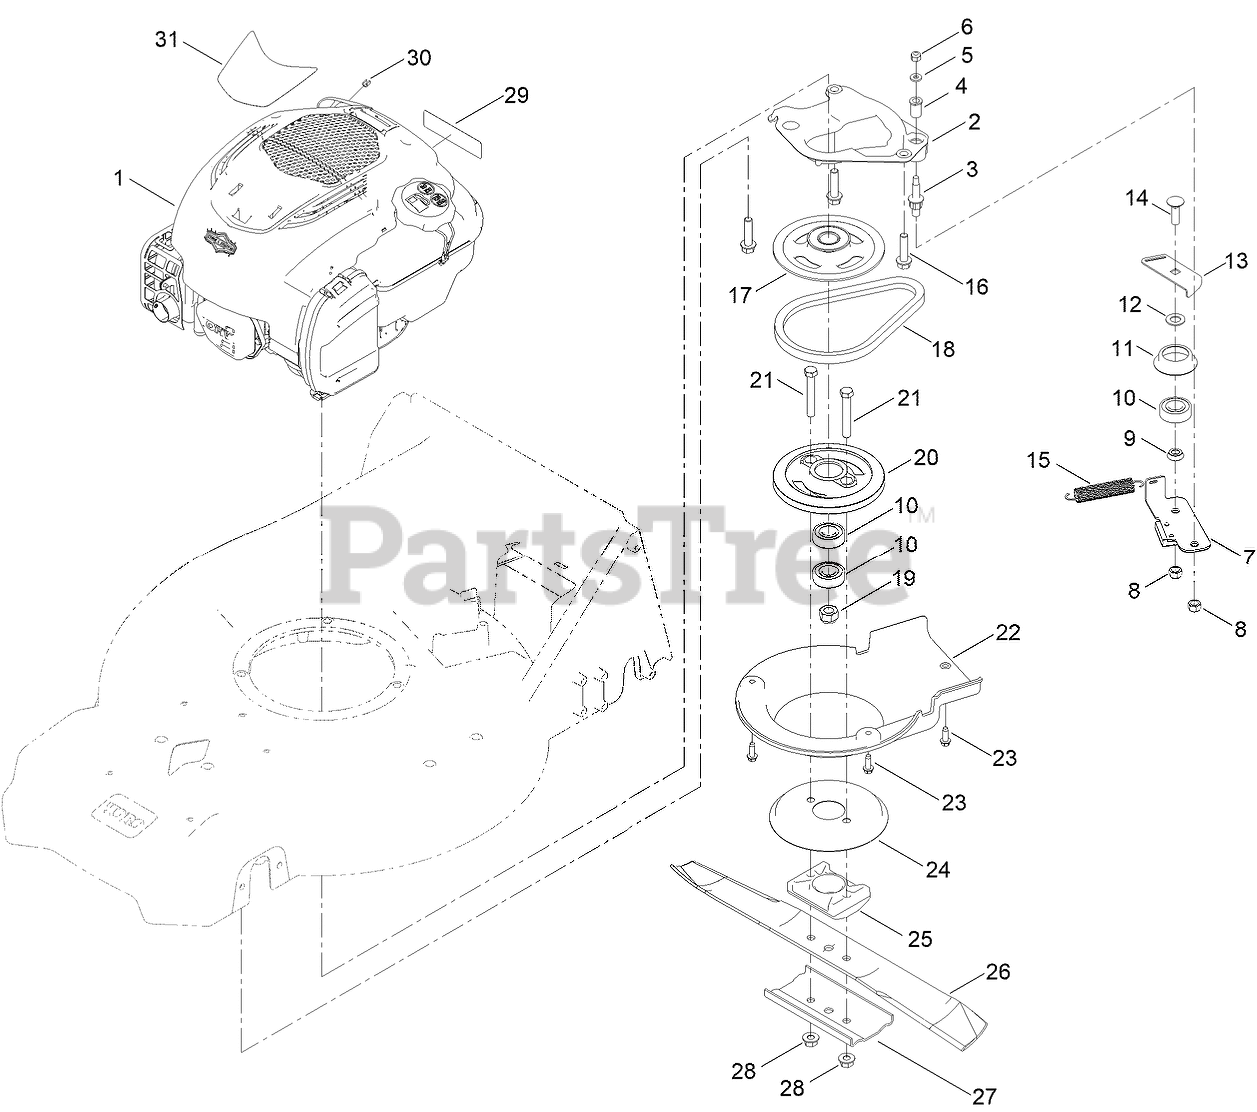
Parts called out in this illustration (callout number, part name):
1	ENGINE-BRIGGS 725 EXI BBC
2	PLATE-ANCHOR
3	BOLT-SHOULDER
4	BUSHING
5	WASHER-FLAT
6	NUT-LOCK, NI
7	PLATE-BRAKE
8	LOCKNUT
9	SPACER-BEARING
10	BEARING-BALL
11	RETAINER-BELT
12	SPACER
13	PLATE-GUIDE
14	BOLT-CARR
15	SPRING-TENSION, BRAKE
16	SCREW-HWH
17	PULLEY
18	BELT
19	NUT-HEX
21	SCREW-HH
23	SCREW-HWHTF
25	SUPPORT-BLADE
26	BLADE-21IN, RECYCLING
27	SUPPORT-BLADE
28	NUT-FLANGE, LOCK
29	DECAL-ARRESTOR, SPARK
30	STOP-ROPE
31	DECAL-BRIGGS, 163CC BBC
